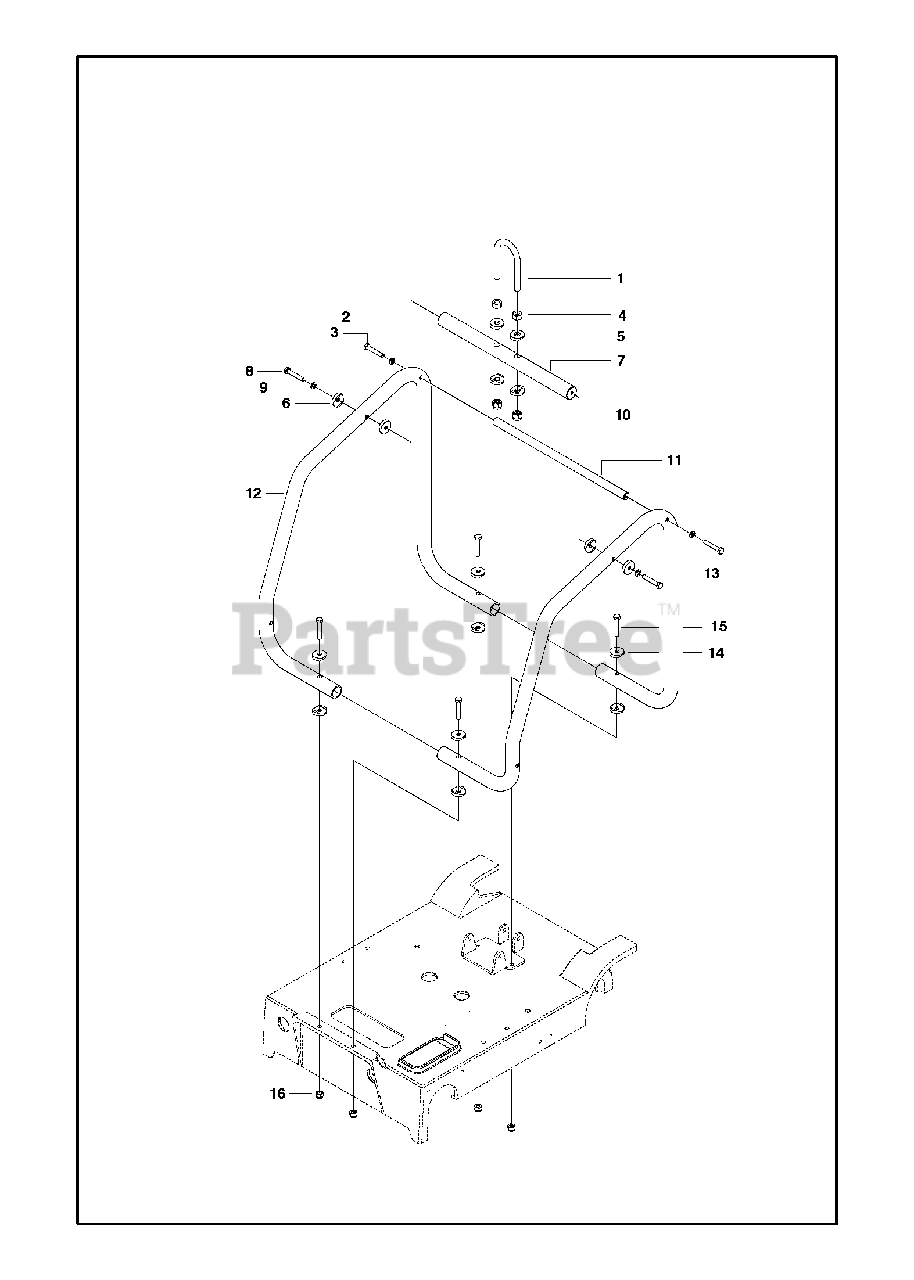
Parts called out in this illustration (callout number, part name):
2	SPRING WASHER
9	SPRING WASHER
16	HEXAGON LOCKING NUT
